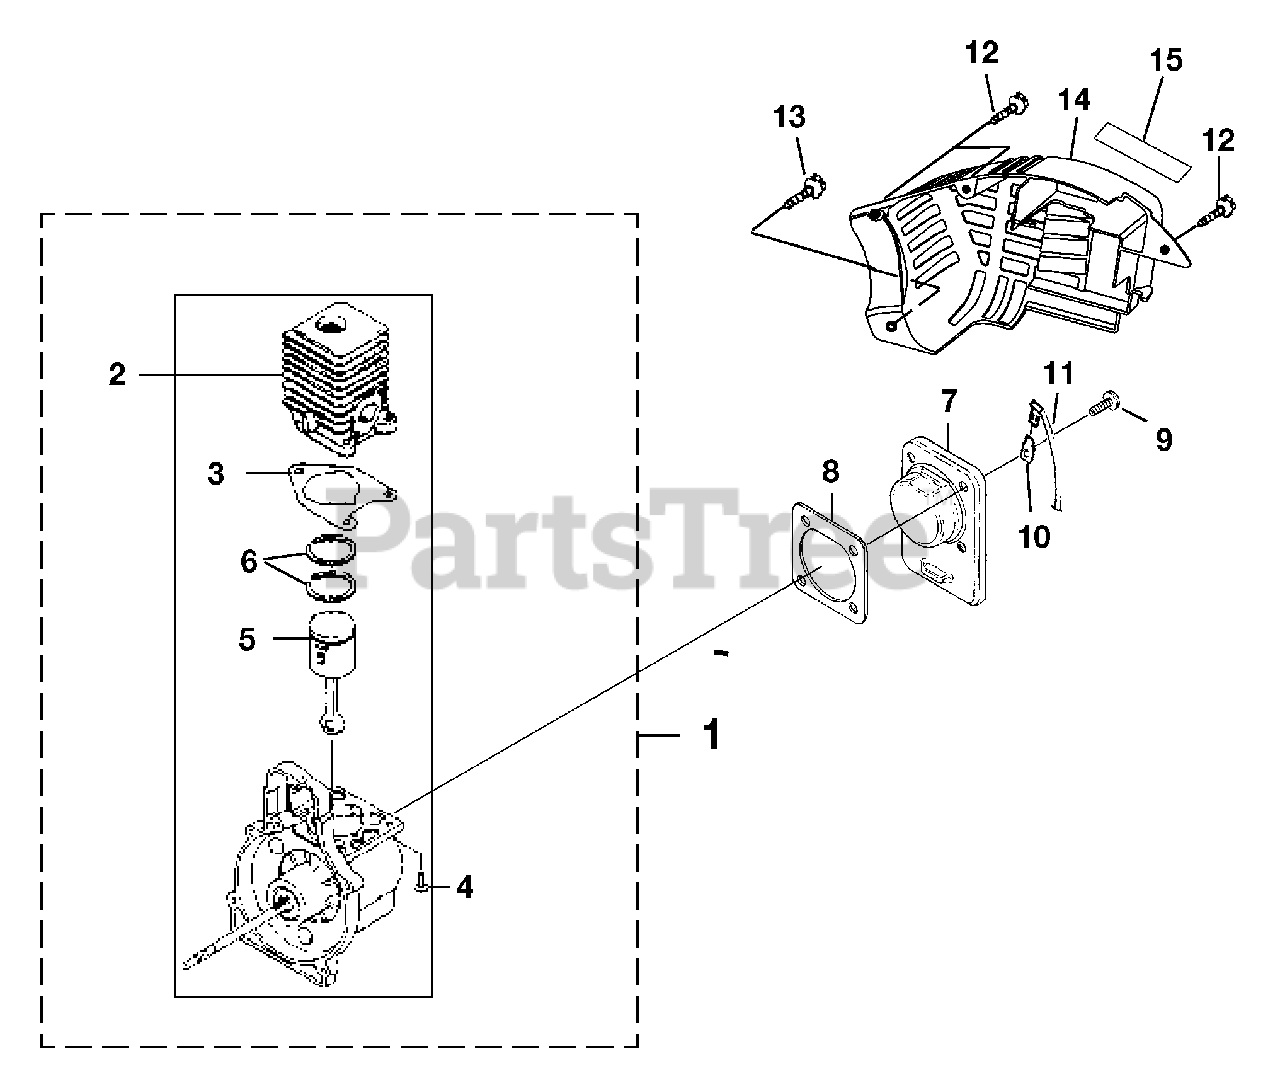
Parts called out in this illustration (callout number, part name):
1	SHORT BLOCK (30cc)
2	30cc CYLINDER
3	CYLINDER GASKET
4	SCREW (12-24 x 3/4 in. TORX PAN HD.)
5	30cc PISTON AND ROD
6	PISTON RING
7	CRANKCASE COVER
8	CRANKCASE GASKET
9	SCREW (10-24 x 9/16 in. PAN HD.)
10	MALE TAB
11	LEAD-GROUND TO HANDLE
12	SCREW (#8 x 1/2 in. PAN HD.)
13	SCREW (#10 x 3/4 in. TORX TRUSS HD.)
15	ZIP START DECAL
